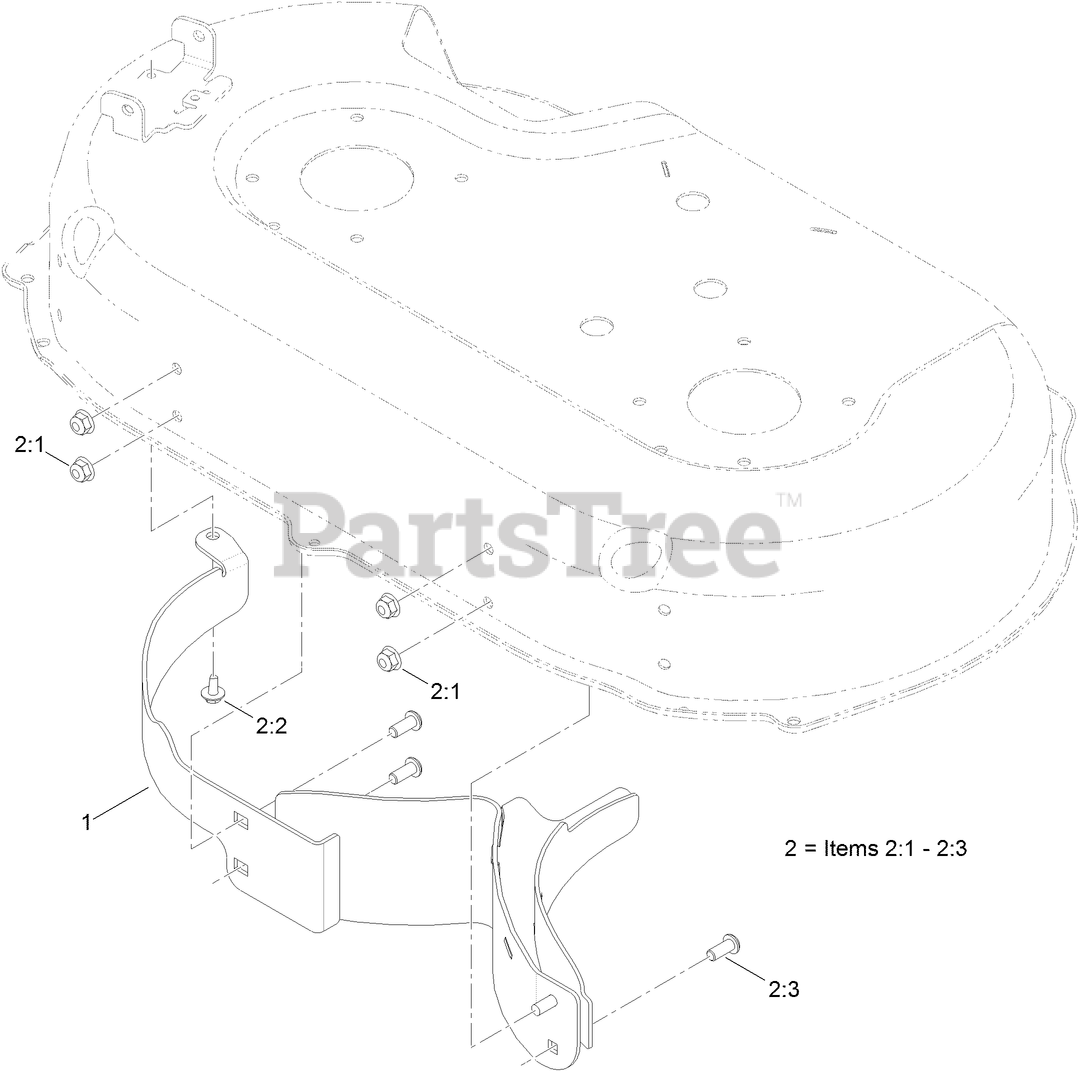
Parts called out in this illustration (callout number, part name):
1	BAFFLE-MULCH
2	BAG-HARDWARE
2:1	NUT-HF, NI
2:2	SCREW-HHFTF
2:3	SCREW-HSBH
